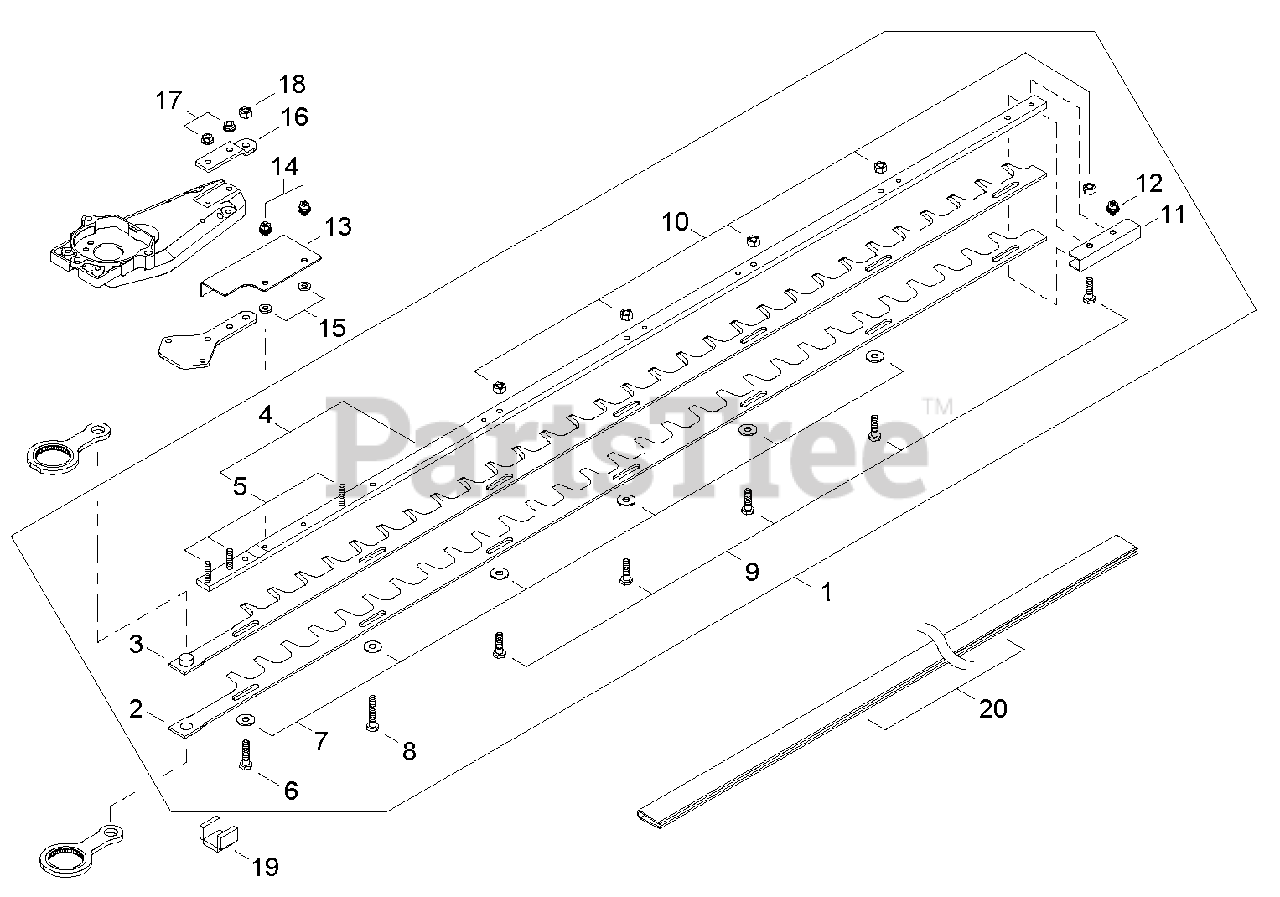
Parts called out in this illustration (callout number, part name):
1	BLADE KIT - 40" (102cm)
2	BLADE - 40" (101cm) CHROME -- LOWER
3	BLADE - 40" (101cm) CHROME -- UPPER
4	SUPPORT, BLADE - 40" (101cm)
5	SCREW - 5X25
6	BOLT - 6
7	WASHER - 6
8	BOLT - 6X32
9	BOLT - 6X20
10	NUT - 6
11	PLATE, GUIDE
12	SCREW - 5X8
13	PROTECTOR
14	SCREW - 5X8
15	WASHER - VINYL
16	PLATE, ANGLE
17	NUT - 5 -- FLANGE
18	NUT - 6
19	SEAL, FELT
20	COVER, BLADE - 40" (102cm)
